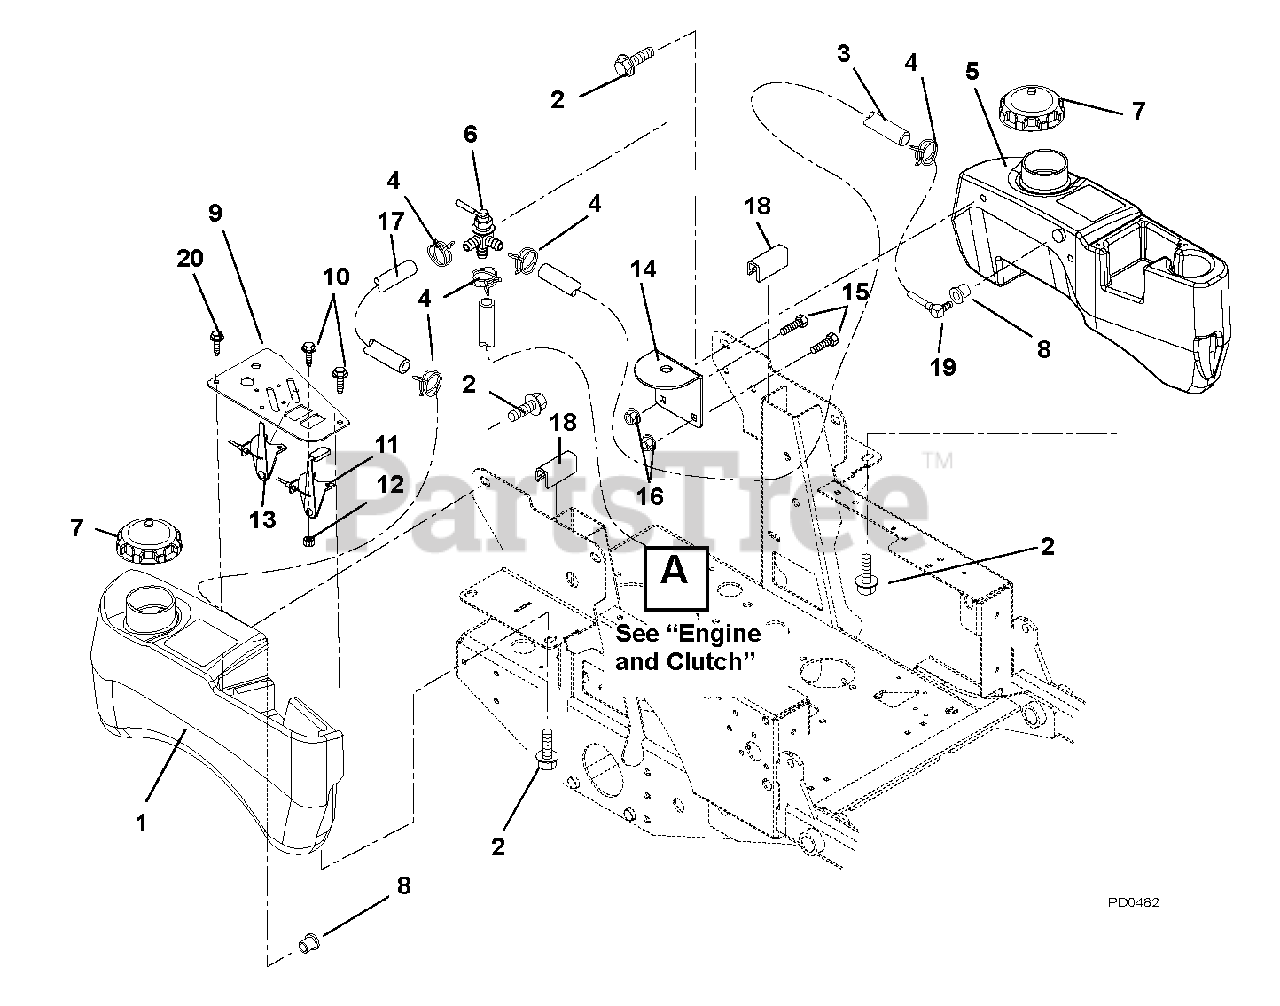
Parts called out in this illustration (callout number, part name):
1	Tank, Fuel Right Hand
2	Bolt, SEMS .31-18 x .62
3	Hose, Gas Line .25" I.D.
4	Hose, Clamp
5	Tank, Fuel Left Hand
6	Valve, Fuel
7	Cap, Fuel Non-Vent Autolock (991105)
8	Grommet (Orange color will not replace black color)
9	Panel, Control
10	Screw, Machine 10-24 x .50 Hex Washer Head
11	Cable, Throttle
12	Nut, Locking Nylon 10-24 with Insert
13	Cable, Choke
14	Bracket, Fuel Valve Mounting
15	Bolt, Round Head Square Neck .31-18 x .75 Grade 5
16	Nut, Nyloc Flange 5/16-18
17	Hose, Gas Line .25" I.D.
18	Cowl Strip 1.75" Long
19	Assembly, Small Tank Fuel Pick-up
20	Screw, Machine 10-24 x .38
